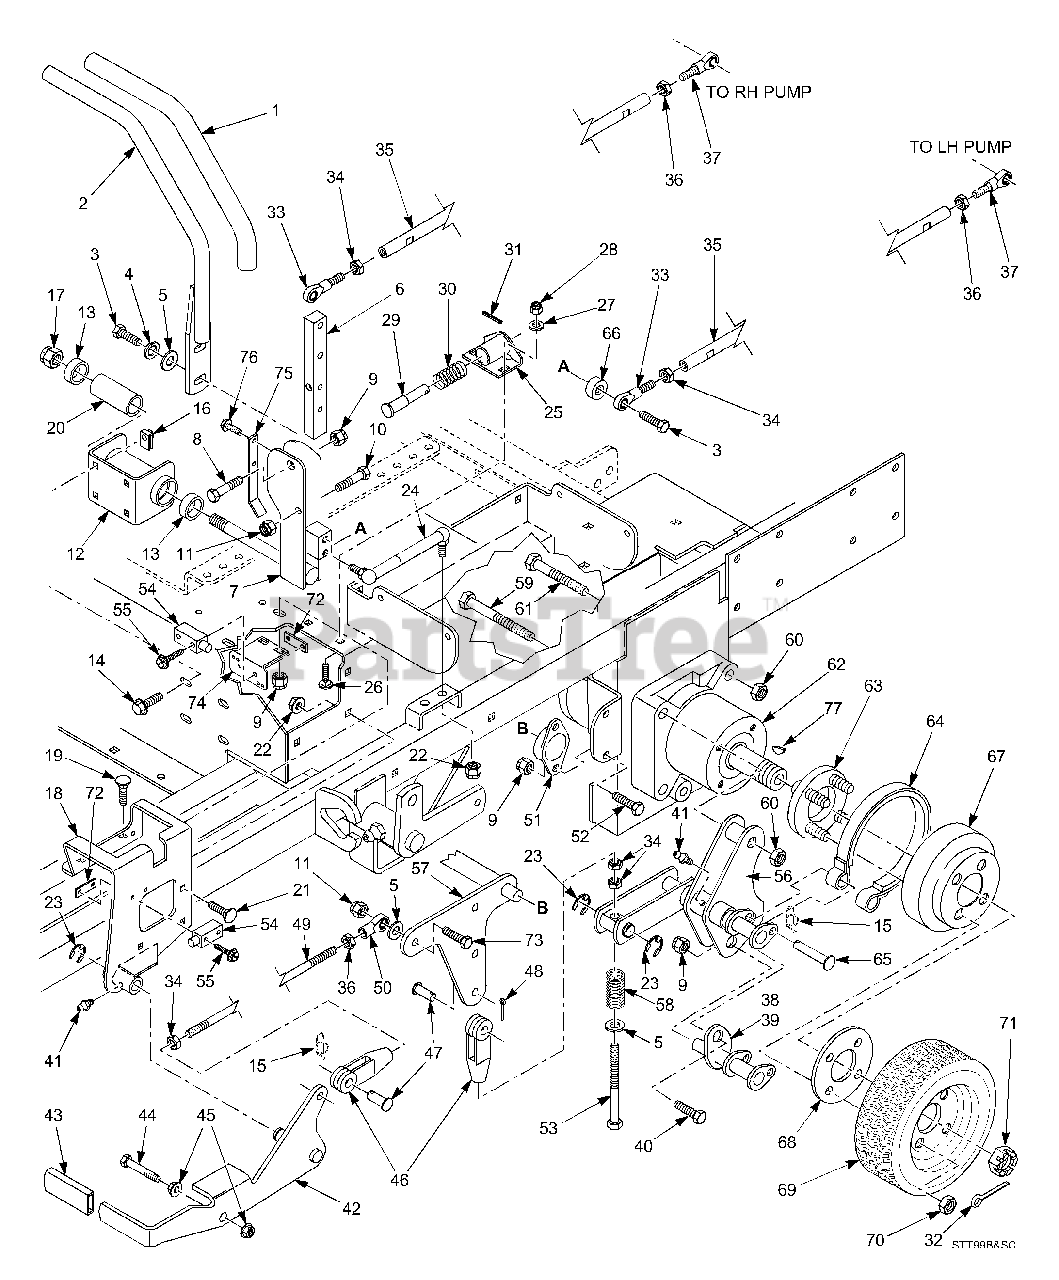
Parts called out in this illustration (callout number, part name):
1	Grip, Handle Bar
2	Handle Bar
3	Bolt, Hex Head 3/8-16 x 1-1/4"
4	Lockwasher, 3/8"
5	Flatwasher. 3/8" (.391 x .938 x .105)
6	Bar, Control Lever
7	Control Lever
8	Bolt, Hex Head 5/16-18 x 2"
9	Nut, Hex Elastic Stop 5/16-18
10	Bolt, Hex Head 3/8-16 x 2"
11	Nut, Hex Elastic Stop
12	Bracket, Control
13	Ball Bearings, Neutral Return
14	Bolt, Hex Head 5/16-18 x 1-1/4"
15	Pin, Rue Cotter 3/8 DIA
16	U-Nut,5/16-18
17	Nut, Hex Elastic Stop 5/8-11
18	Bracket, Control Lever LH
19	Bolt, Carriage 5/16-18 x 1"
20	Spacer, Bearing
21	Bolt, Carriage 5/16-18 x 3/4"
22	Nut, Hex Serrated Flange 5/16-18
23	Ring, Retaining 5/8" External "E"
24	Gas Damper
25	Bracket, Neutral Return
26	Bolt, Carriage 1/4-20 x 3/4"
27	Flatwasher, 1/4" (.312 x .750 x .065)
28	Nut, Hex Elastic Stop 1/4-20
29	Pin, Retaining Spring
30	Spring
31	Roll Pin, Spring 5/32 x 3/4"
32	Pin, Cotter 9/16 x 1-1/2"
33	Rod End, Male 3/8-24 RH THD.
34	Nut, 3/8-24 RH THD.
35	Tube, Control Link
36	Nut, Hex 3/8-24 LH THD.
37	Rod End, Male 3/8-24 LH THD.
38	Brake Linkage Weldment LH
39	Brake Linkage Weldment RH
40	Bolt, Hex Head 5/16-18 x 1"
41	Grease Fitting
42	Lever, Parking Brake
43	Grip, Parking Brake
44	Bolt, Hex Head 3/8-16 x 2-3/4"
45	Nut, Hex Serrated Flange 3/8-16
46	Clevis, Traction Control
47	Pin, Clevis 3/8-16 x 1-1/16"
48	Pin, Cotter 3/32 x .75
49	Rod, Parking Brake
50	Rod End, LH THD.
51	Bushing, Self Align
52	Bolt, Hex Head 5/16-18 x 3/4"
53	Bolt, Hex Head 3/8-24 x 5-1/4", 2-3/4" Thread
54	Switch
55	Screw, Hex SLTD WSHR Head #10-32 x 3/4"
56	Brake Linkage, LH
57	Bellcrank, Brake Actuator
58	Spring
59	Bolt, Hex Head 1/2-13 x 3-1/2"
60	Locknut, Hex 1/2-13 Center Lock
61	Bolt, Hex Head 1/2-13 x 2-1/2"
62	Wheel Motor, Ross
63	Wheel Hub Assembly
64	Brake Band Assembly
65	Pin, Clevis 3/8" Dia. x 2"
66	Spacer
67	Brake Drum
68	Spacer, Wheel
69	Wheel Assembly 24 x 12-12 Turf Master
70	Lug Nut, 1/2-20
71	Nut, Hex Castle
72	Plate, Threaded
73	Bolt, Hex Head 3/8-16 x 1-1/2"
74	Bracket, Switch Mounting
75	Bracket, Switch Actuator
76	Bolt, Hex Serrated Flange 5/16-18 x 3/4"
77	Key, Woodruff 5/16 x 1"
